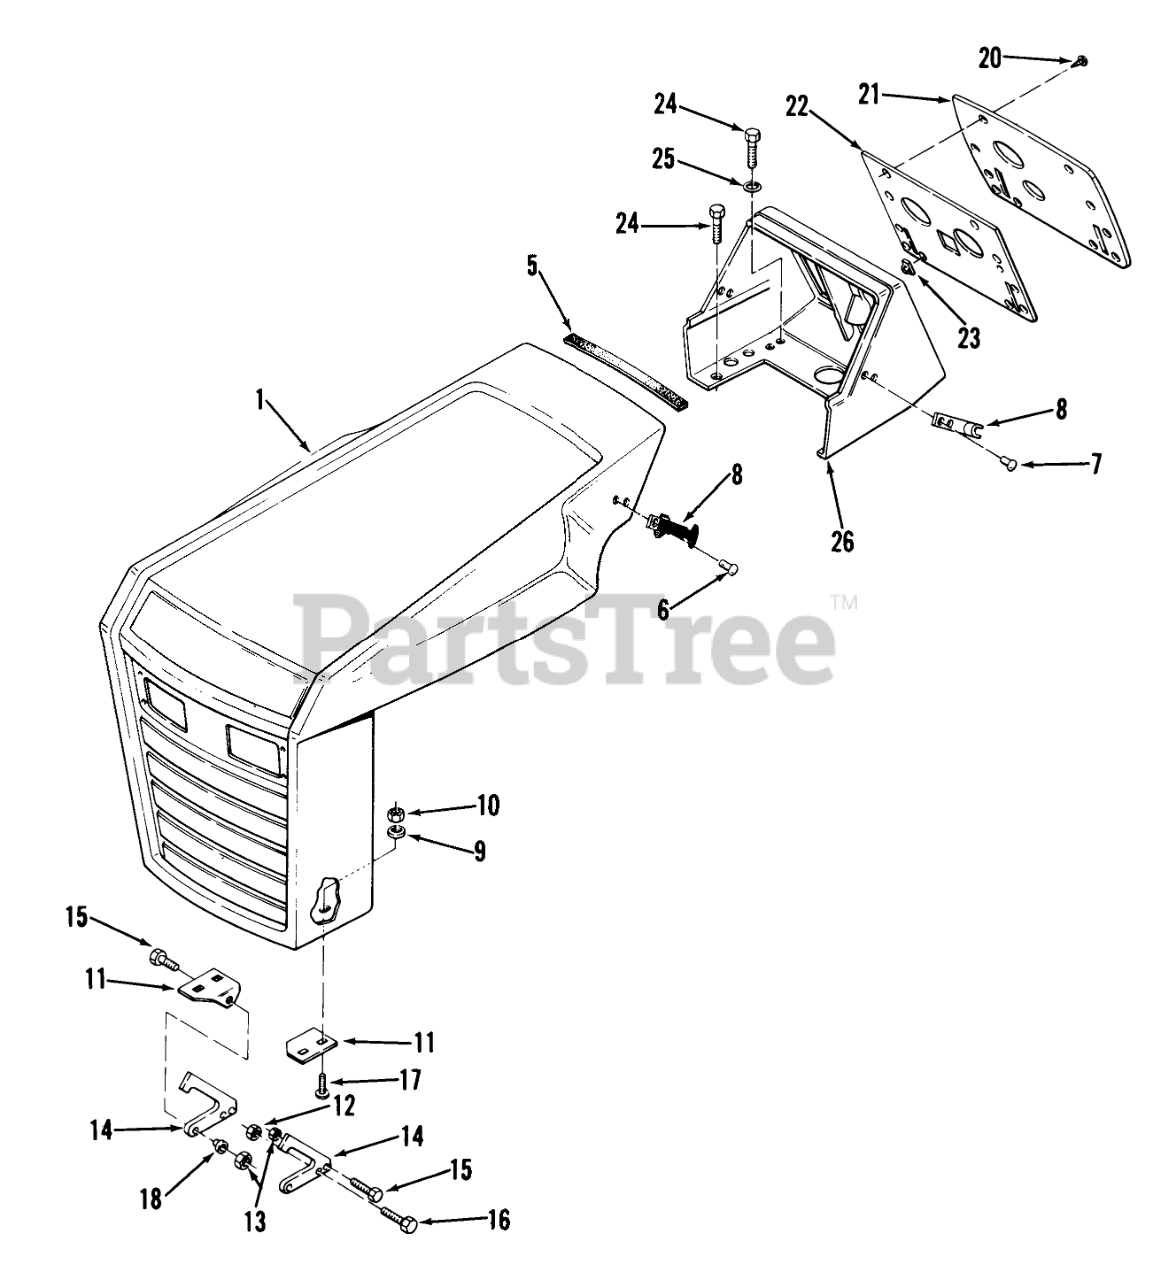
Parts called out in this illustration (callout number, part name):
5	TRIM-CONSOLE
6	RIVET -4
7	RIVET
8	ASSY-FLEX DRAW LATCH
10	Nut
11	BRKT-HOOD PIVOT LH
11	BRKT-HOOD PIVOT RH
12	Nut
13	Nut
14	BRACKET-HOOD SUPT
15	Bolt
16	Bolt
17	Bolt-Carriage
18	BUSHING-PIVOT
20	SCREW BLACK
21	PLATE-INSTRUMENT
22	Back-Up Plate
23	SPEED NUT
24	SCREW
25	WASHER 5/16 SAE
26	Console
